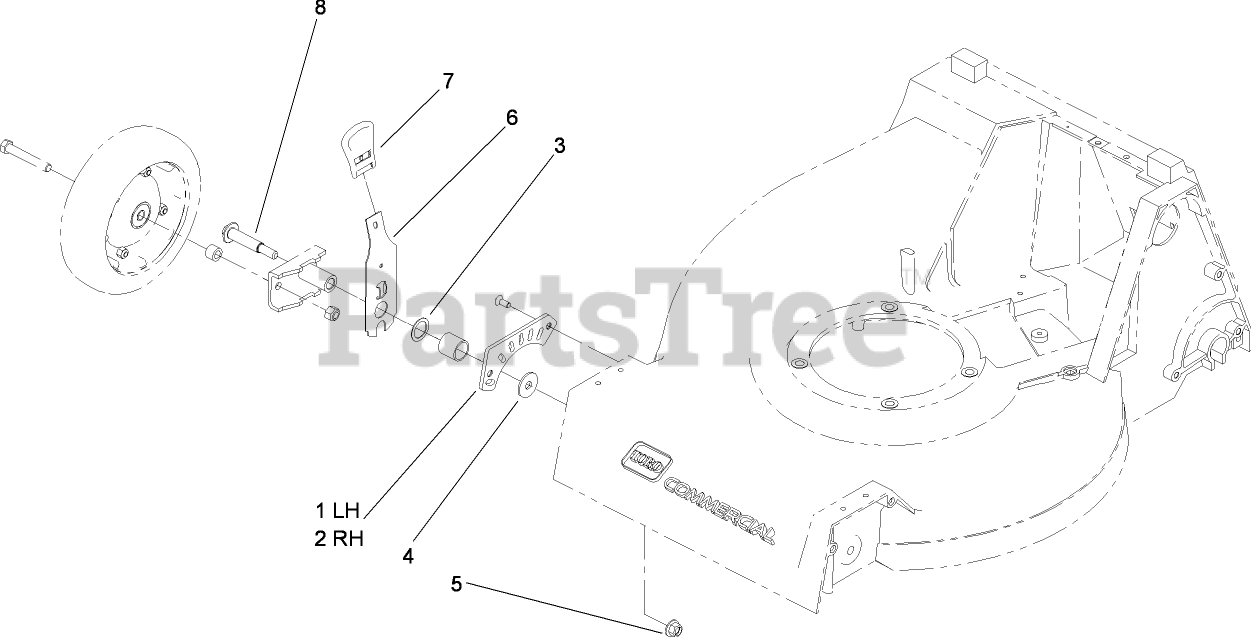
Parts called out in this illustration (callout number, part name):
1	PLATE-FRONT HOC, LH
2	PLATE-FRONT HOC, RIGHT
3	WASHER
4	WASHER
5	NUT-LOCK
6	FRONT SPRING ARM ASM
7	KNOB-HOC
8	SCREW-SHOULDER
